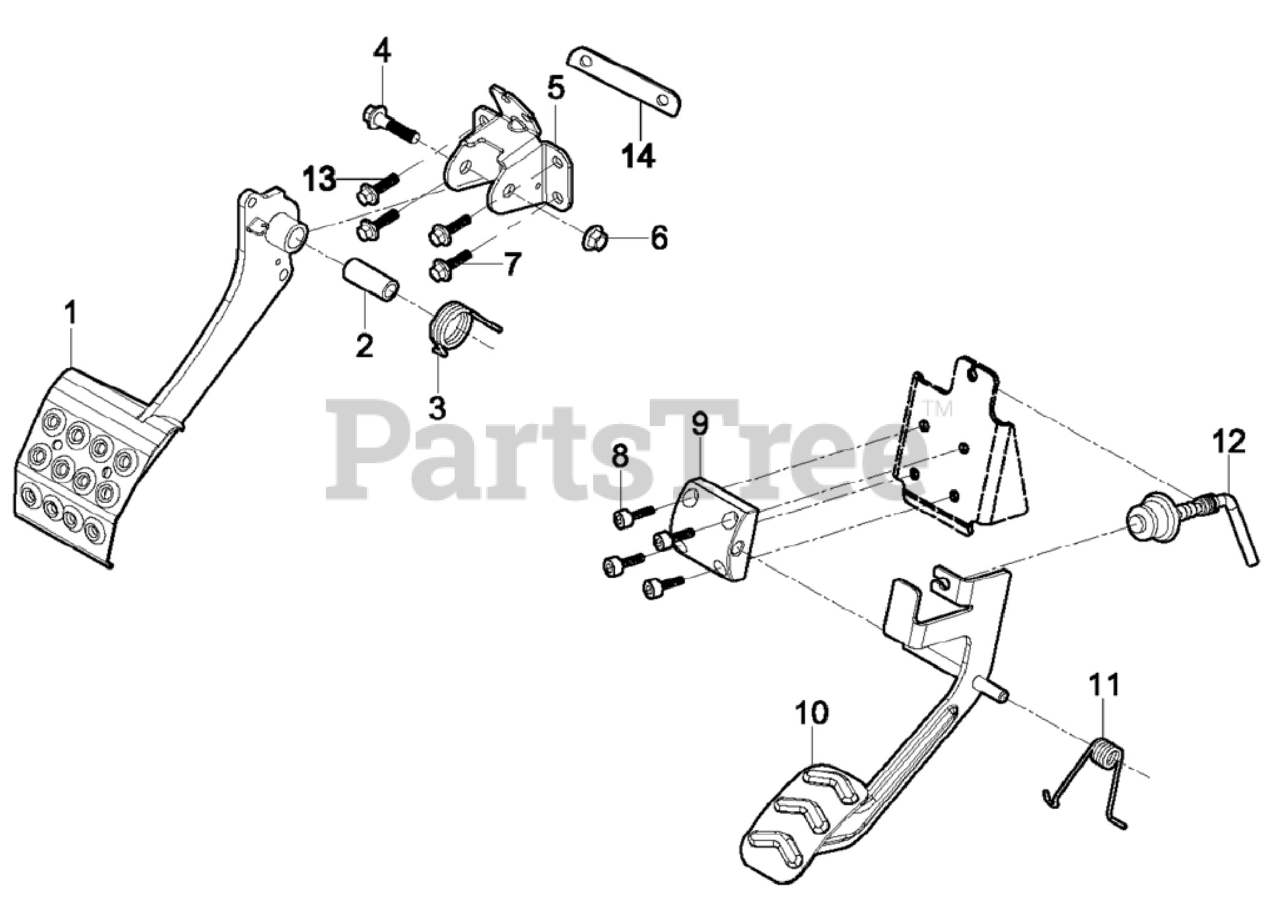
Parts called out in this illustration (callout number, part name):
1	BRAKE PEDAL WELDING KIT
2	SPACER 10.2x15x35.5
3	TORSION SPRING J
4	Hexagon Flange Bolt M10x1.25x60
5	BRAKE PEDAL BRACKET PLATED
6	LOCK NUT M10x1.25
7	Hexagon Flange Bolt M8X20
8	Socket Hexagon Head Screw M6x20
9	THROTTLE PEDAL BRACKET PLATED
10	ACCELERATOR PEDAL WELDING KIT
11	TORSION SPRING 2.5x15.5x66
12	THROTTLE CABLE AH
13	Flange bolt M8X25
14	PEDAL BRACKET PAD
